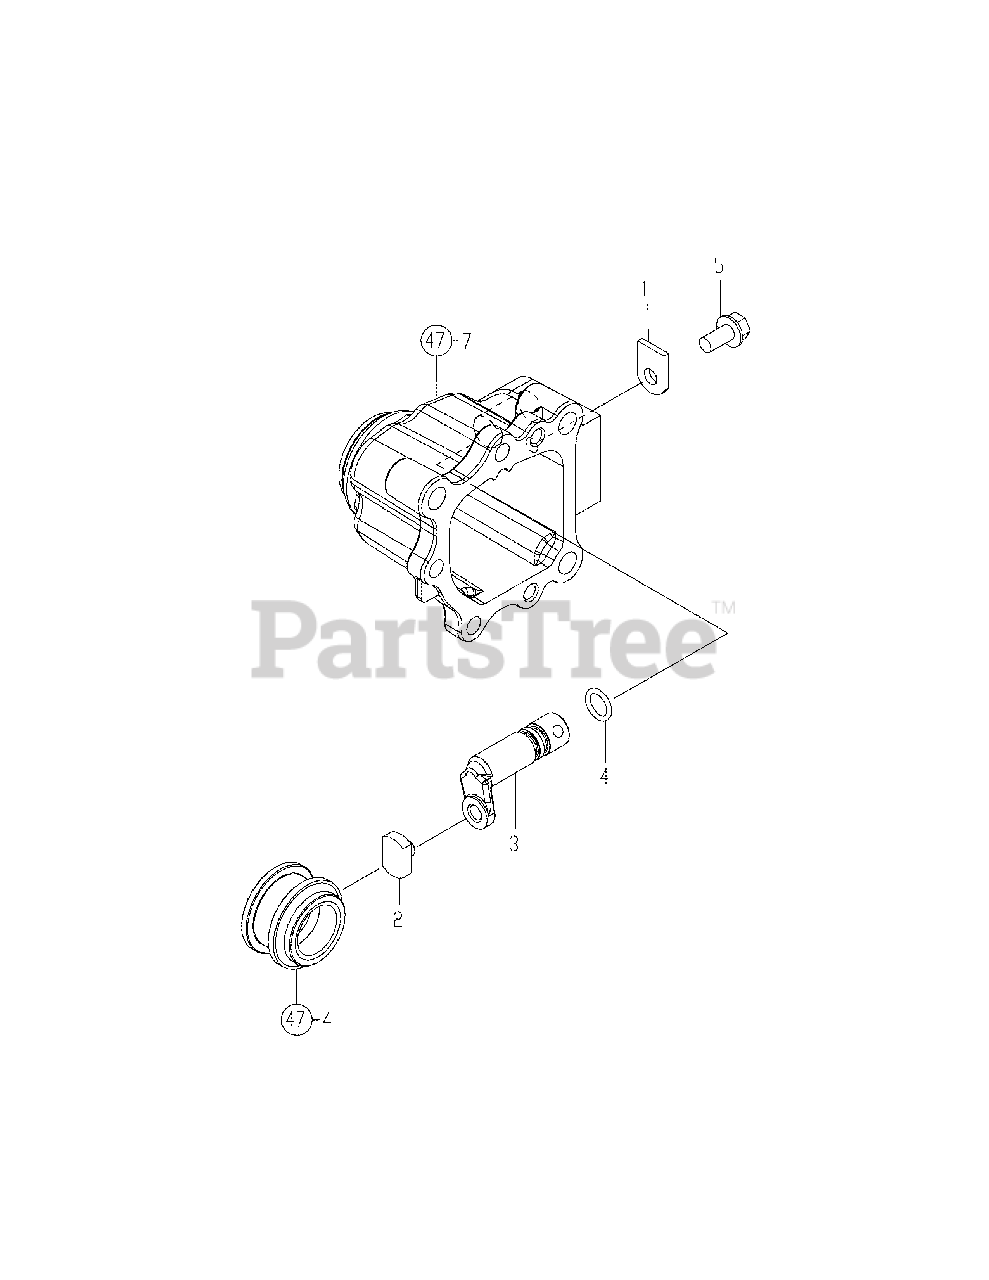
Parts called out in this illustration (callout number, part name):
2	Block, Shift Front
3	Shift, Shaft 4Wd
4	Packing, P 12.5
